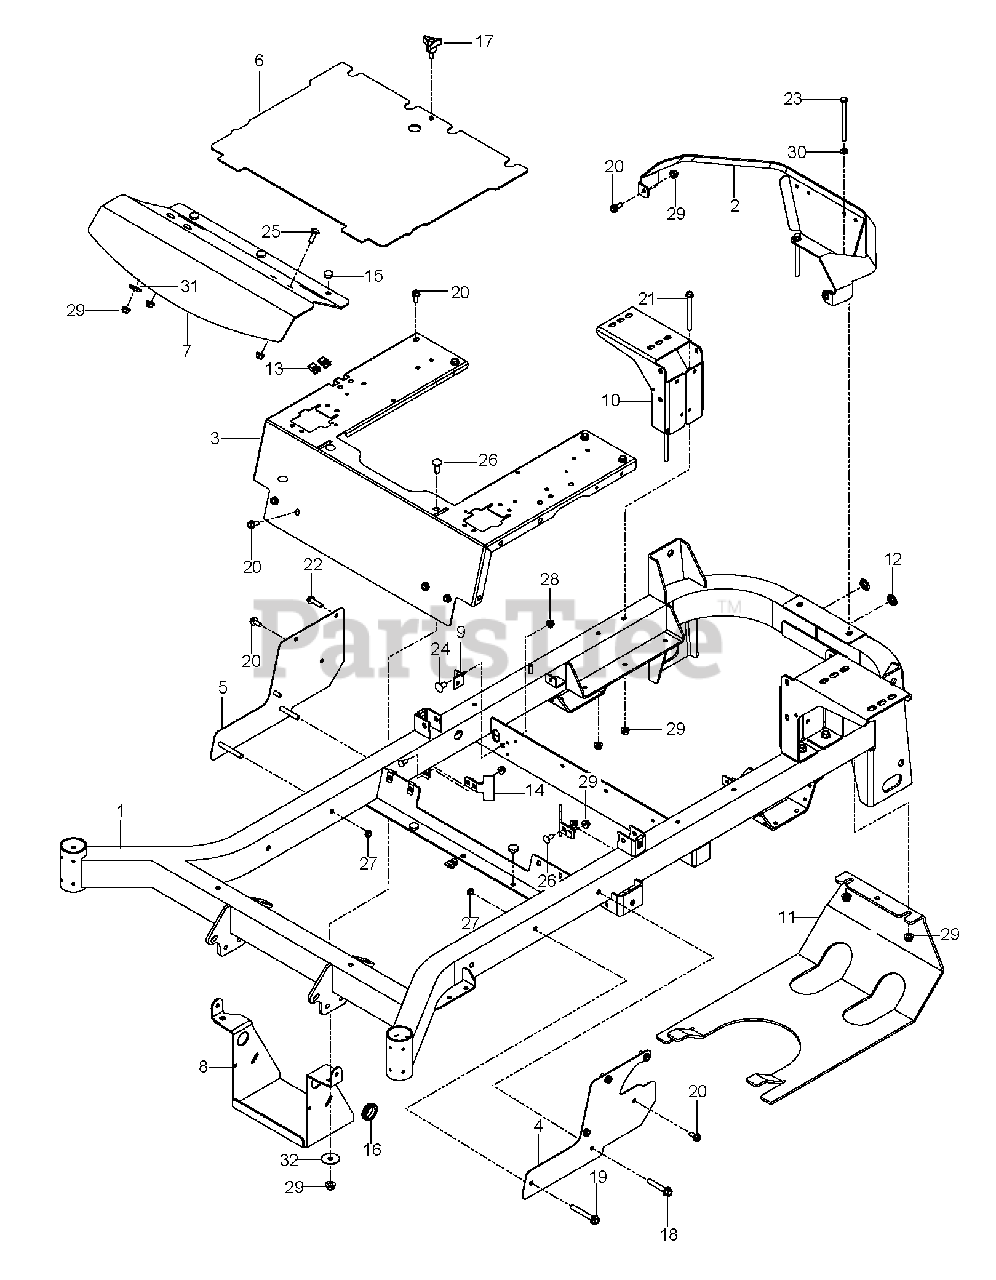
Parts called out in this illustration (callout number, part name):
1	KIT.FRAME.W/DECALS.X668
2	GUARD.PNT.REAR.MZ.GRAY
3	SUPPORT.PNT.SEAT.CONTROL.ORNG
4	BRACKET SIDE, LT ORANGE
5	BRACKET.PNT.SIDE.RT.JNX667
6	PLATE, FLOOR W/DECALS
7	PLATE, FOOTREST
8	BRACKET.PNT.BATTERY.BLK
9	BRACKET.DAMPENER.BLACK
10	MOUNT, TANK, ZT BLK
11	GUARD SKID PNT 498
12	CAP.PLUG.BP-1.BLACK
13	U-CLIP 5/16-18 NUT RETAINER
14	STOP, DECK, EZ+
15	GROMMET, BUMPER
16	RUBBER GROMMET
17	KNOB W/STUD
18	HHFS 3/8-16 X 2.5 GR 5 ZD
19	HHFS 3/8-16 X 2-3/4 GR5 ZD
20	HHFS 5/16-18 X 3/4
21	BOLT.HEX.FLNG.5/16-18X3.75
22	HHFS 5/16-18 X 1.25 TPBLT GD 5
23	HCS 5/16C X 4
24	RHSNB 3/8-16 X 3/4 GR 5 BLK ZN
26	BOLT 5/16-18 X3/4 ZN/YEL GR 5
27	NUT HEX 3/8-16 NYLON, THIN
28	NUT 3/8-16 HEX FLG NYLOC ZD
29	5/16-18 NYLOC FLANGE NUT
30	WASHER
31	WASHER 1/2" FLAT
32	WASHER.13/32X1-1/2X16GA
